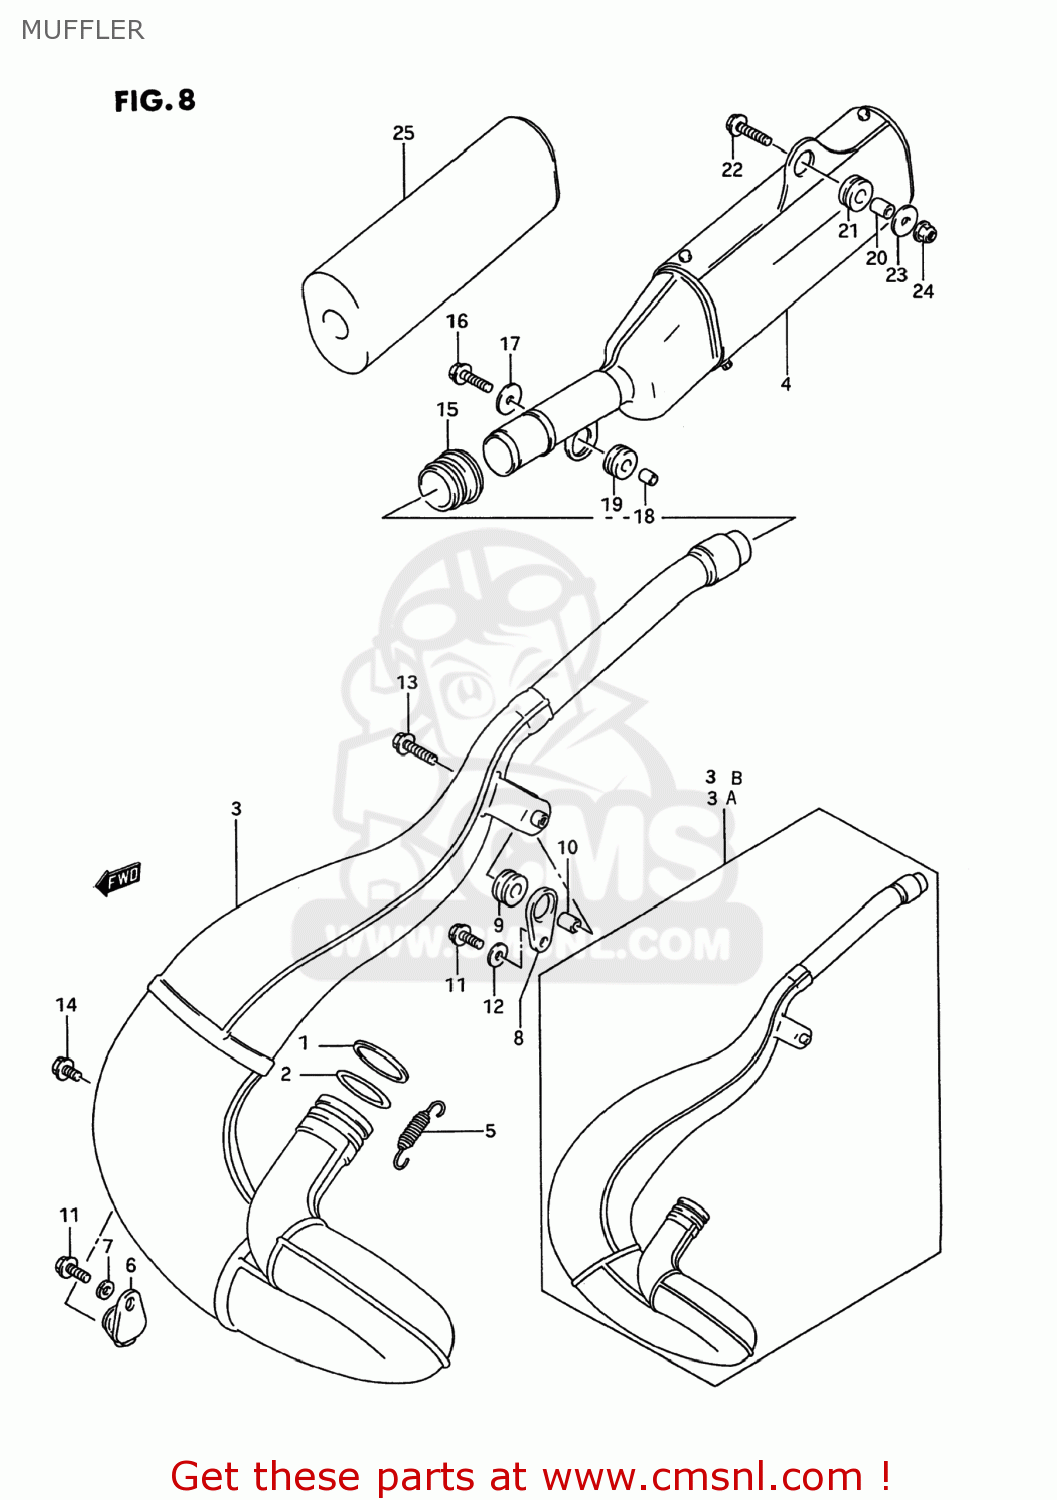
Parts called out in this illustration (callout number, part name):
1	WASHER,EXHAUST PIPE
2	O RING,EXHAUST PIPE
3	BODY,MUFFLER 1ST
3A	BODY,MUFFLER,FIRST
3B	BODY,MUFFLER,FIRST
4	BODY COMP,MUFFLER,SECOND.
5	SPRING
6	DAMPER,MUFFLER SUPPORT
7	WASHER
8	PLATE,MUFFLER MTG
9	CUSHION,MUFFLER
10	SPACER (6.4X9X13.5)
11	BOLT
12	WASHER
13	BOLT
14	BOLT
15	CONNECTOR,MUFFLER
16	BOLT
17	WASHER (6.5X24X1.6)
18	SPACER (6.8X10X9)
19	CUSHION
20	SPACER(6.5X11.5X13)
21	CUSHION
22	BOLT
23	WASHER (6.5X24X1.2)
24	NUT
25	SILENCER,MUFFLER
